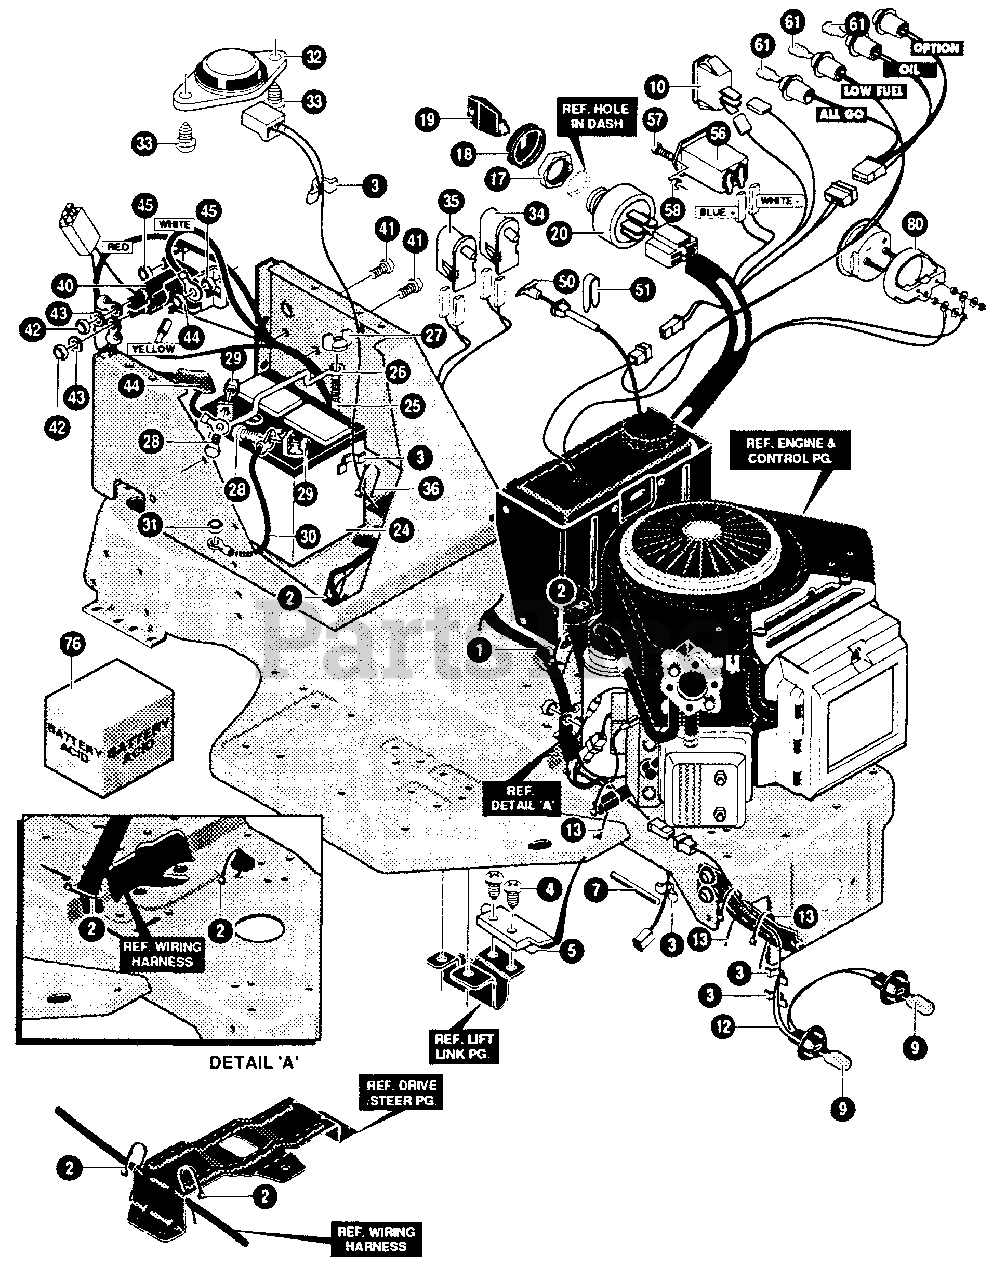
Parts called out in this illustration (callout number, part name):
1	HARN,WRNG EURO BS VTWN M/C AMP
2	TIE, CABLE BLACK NYLON 5.62L
3	PRESS CLIP, 1.380LG .255ID
4	SCREW, #12 X .50 PHPNHTAP BLK
5	SWITCH,SCR MNT DP NC NO BLK
9	BULB, HEADLAMP
10	LIGHT SWITCH ON,OFF PANEL MNT
12	ASSY,LIGHT WIRE-1/4 TURN
13	TIE. CABLE BLACK NYLON 5.62L
17	NUT, 5/8-8ACME DELTA FOR BOOT
18	BOOT, IGN SWITCH
19	KEY,IGNITION
20	SWITCH-IGN.(AFTER FIRE) 3 POSN
24	BATTERY, 12V
25	ROD, BATTERY
26	ROD, BATTERY TOP .209DIA
27	NUT, WING 1/4-20 NYLON
28	SCREW, 1/4-20X .75 HHC
29	NUT, 1/4-20 REGHEXKEPS
30	WIRE, GROUND, 12.5'
31	NUT, 5/16-18 HEXKEPS
32	SWITCH. SEAT
33	SCREW, 1/4-20X .38PHPNHMA
34	SWITCH, SNAP MNT NC 140 BLUE
35	SWITCH,SNAPMNT NO 055/ 116GRY
36	TIE. CABLE BLACK NYLON 5.62
40	SOLENOID
41	SCREW, 1/4-20X .75 HXSEMMA
42	NUT, 5/16-24 REGHEX
43	WASHER, EXLK .320X.61X 03
44	NUT, 1/4-20 REGHEXKEPS
45	NUT, 1/4-20 REGHEXCTRLK
50	CHOKE CONT BS TWIN ERO LONG
51	CLIP,CHOKE CONTROL
56	MINIATURE HOUR METER 4-40V DC
57	SCREW, #6-32X 50 PHPNMA CRSS
58	NUT, #6-32 HEXKEPS
61	BULB, INDICATOR
76	BATTERY ACID PACK, 80 OZ
80	AMMETER ASSY=>309373,121685
